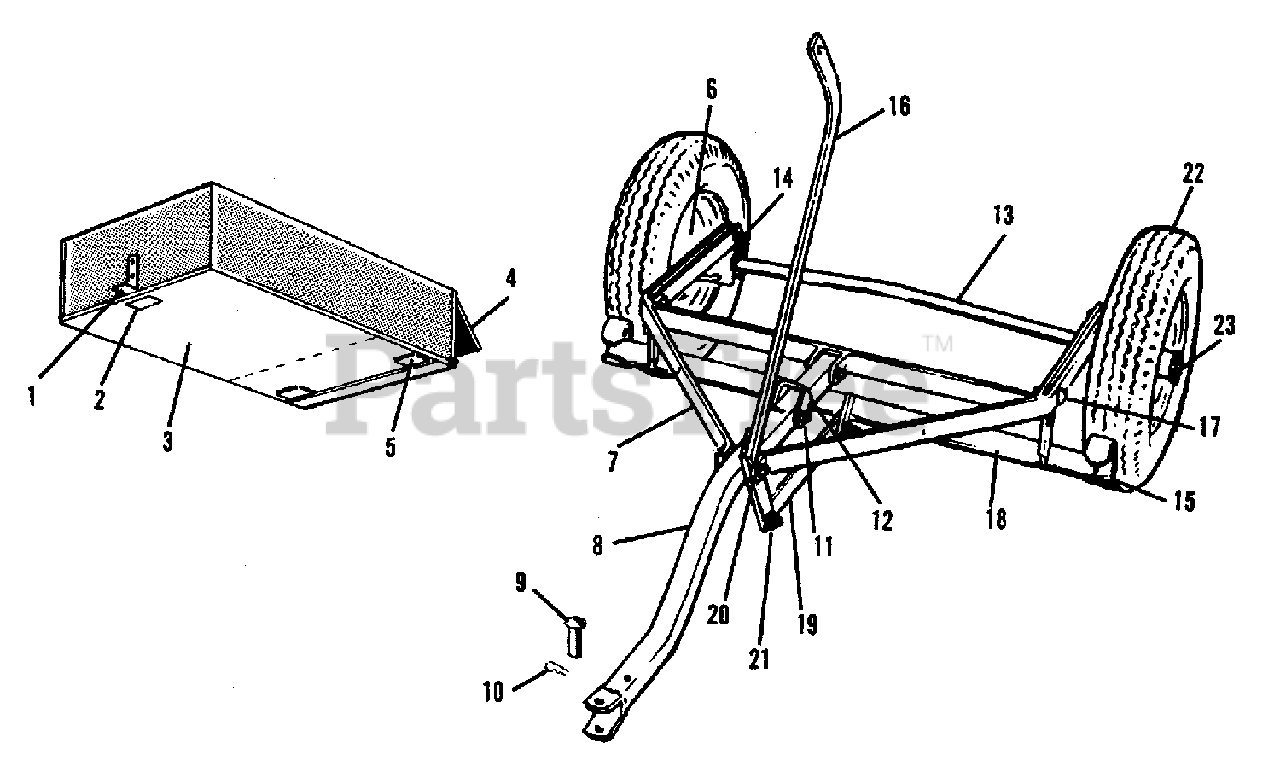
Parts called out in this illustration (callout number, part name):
1	PLATE, Box Catch
1	LOCKWASHER, 3/8
1	CAPSCREW, 3/8NC x 1
1	NUT, 3/8NC
2	PLATE, Box Guide
3	BODY, Trailer
4	END GATE, Trailer
5	PIVOT ASSEMBLY, Box
5	CAPSCREW, 3/8NC x 1
5	NUT, 3/8NC
5	LOCKWASHER, 3/8
5	WASHER, 7/16 x 1 x #14
6	WHEEL, 4", Less Tire
6	BEARING, Wheel
7	FRAME ASSEMBLY, Trailer
8	TONGUE ASSEMBLY, Trailer
8	CAPSCREW, 3/8NC x 2-1/4
8	NUT, 3/8NC
8	LOCKWASHER, 3/8
9	PIN, Tongue
10	CLIP, Spring
11	SPRING, Box Catch
11	CAPSCREW, 3/8NC x 7/8
11	NUT, Lock, 3/8NC
11	WASHER, 7/16 x 1 x #14
12	CLEVIS, Box Catch
13	AXLE ASSEMBLY, Trailer
14	PIN, Lock, Axle
15	CLIP, Spring Axle Pin
16	HANDLE ASSEMBLY, Brake
16	CAPSCREW, 3/8NC x 2-3/4
16	LOCKWASHER, 3/8
16	NUT, 3/8NC
16	WASHER, 7/16 x 1 x #14
17	PIN, Pivot
17	PIN, Cotter, 1/8 x 1
18	BRAKE ASSEMBLY
19	LINK, Brake
19	CAPSCREW, 5/16NC x 1-1/2
19	WASHER, 11/32 x 1-1/2 x #12
19	NUT, Lock, 5/16NC
20	SPACER, Handle
21	SPRING, Brake Link
22	TIRE, 4.00 x 8, 2 ply
